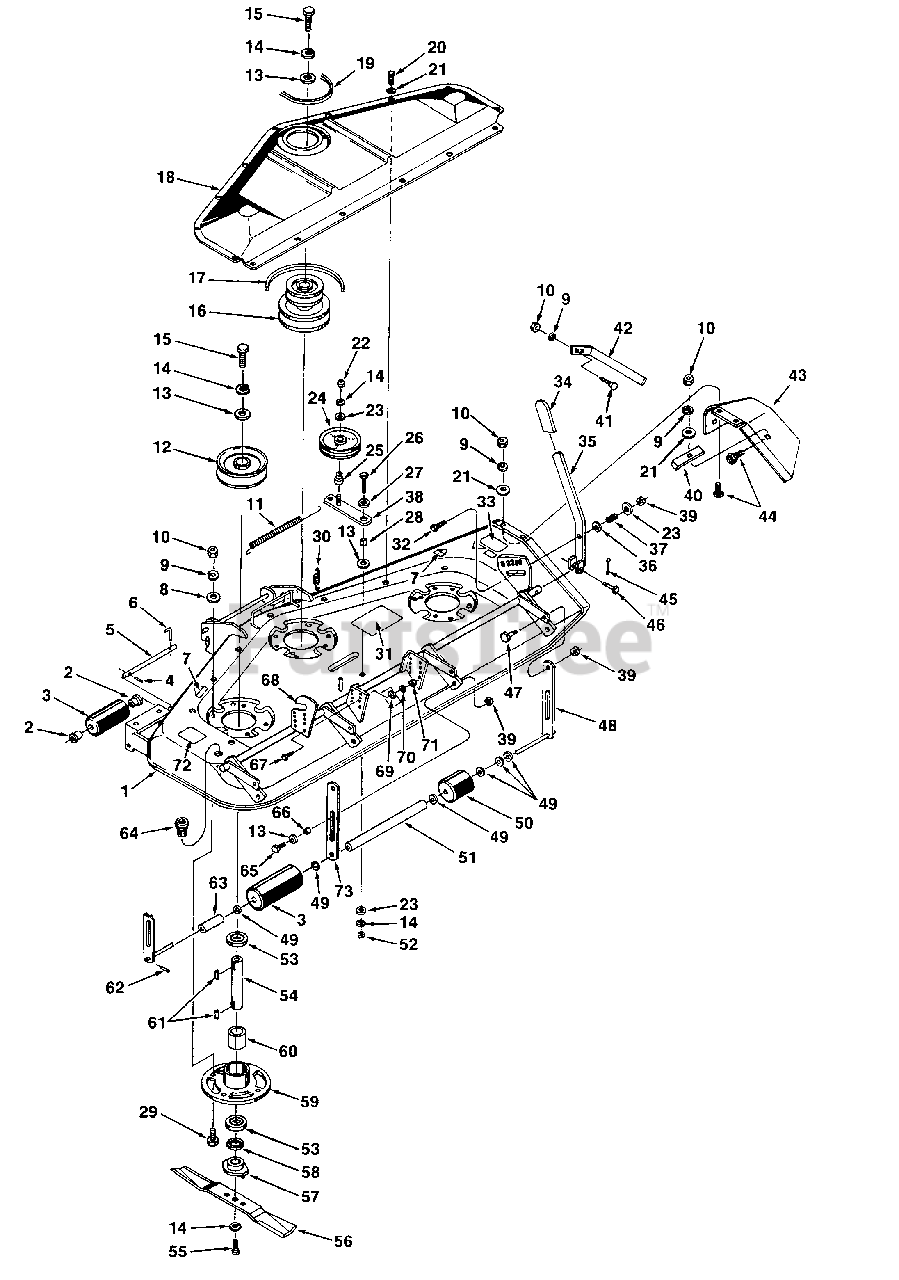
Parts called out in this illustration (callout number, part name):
1	MOWER HOUSING ASSEMBLY
2	BUSHING- Roller
3	ROLLER- Assy (long)
4	PIN- 3/16 x 13/16 roller
5	SHAFT- Front roller
6	PIN- Hold
7	DECAL- CPSC warning
8	WASHER- Flat
9	WASHER- Lock 5/16 hvy
10	NUT- 5/16-18 hex
11	SPRING- Idler pulley
12	PULLEY- R.H. & L.H. cutter drive
13	WASHER- Pulley retainer
14	WASHER- Lock 3/8 hvy
15	SCREW- 3/8-24 x 1 1/4 hex hd cap
16	PULLEY- Mower drive
17	BELT- Cutter drive
18	Cover- Pulley
19	BELT- V engine to mower
20	SCREW- 1/4-20 x 9/16 hex hd thd forming
21	WASHER- 5/16 sae flat
22	NUT- 3/8-16 hex jam
23	WASHER- 3/8 std flat
24	IDLER PULLEY ASSEMBLY
25	STANDOFF- Idler
26	SCREW- 3/8-16 x 1 1/4 C/R truss hd
27	WASHER- Arm retaining
28	SPACER- idler arm pivot
29	SCREW- 5/16-18 x 3/4 hex hd
30	SPRING- Hitch latch (front)
31	DECAL- Instruction
32	SCREW- 3/8-16 x 2 hex hd cap
33	DECAL- Danger
34	GRIP- height adjusting handle
35	CONTROL LEVER- Cutter height
36	WASHER- Control lever
37	SPRING- Control lever latch
38	WELDMENT- idler arm
39	NUT- 3/8-16 hex gripco c/lock
40	BRACKET- Deflector clamping
41	BOLT- 5/16-18 x 7/8 rd hd
42	GUARD- Toe
43	DEFLECTOR- Discharge chute
44	Bolt- 5/16-18 x 3/4 reg carr.
45	PIN- 1/8 x 1/2 cotter
46	PIN- Pivot
47	PIN- Lift
48	REAR ROLLER SHAFT & ARM ASSEMBLY
49	WASHER- 1/2 std sae flat
50	ROLLER ASSEMBLY (short)
51	SPACER- Rear roller outer
52	NUT- 3/8-16 hex
53	BEARING- Cutter shaft
54	SHAFT- Cutter Side
55	SCREW- 3/8-24 x 1 hex hd cap
56	CUTTER BAR SET
57	ADAPTOR- Blade
58	WASHER- Flat
59	CUTTER HOUSING ASSEMBLY
60	SPACER- Bearing
61	KEY- Par. 3/16 x 3/16 x 13/16
62	PIN- 1/8 x 7/8 roll
63	SPACER- Rear roller center
64	FITTING- Washout
65	SCREW- 3/8-16 x 1 1/4 hex hd cap
66	SPACER- Rear roller guide
67	SCREW- 1/4-20 x 7/8 hex
68	BRACKET- Rear hanger
69	WASHER- 1/4 flat bracket mounting
70	WASHER- lock 1/4 hvy bracket mounting
71	NUT- 1/4-20 hex bracket mtg
72	DECAL- Danger
73	ARM- Rear roller mounting
